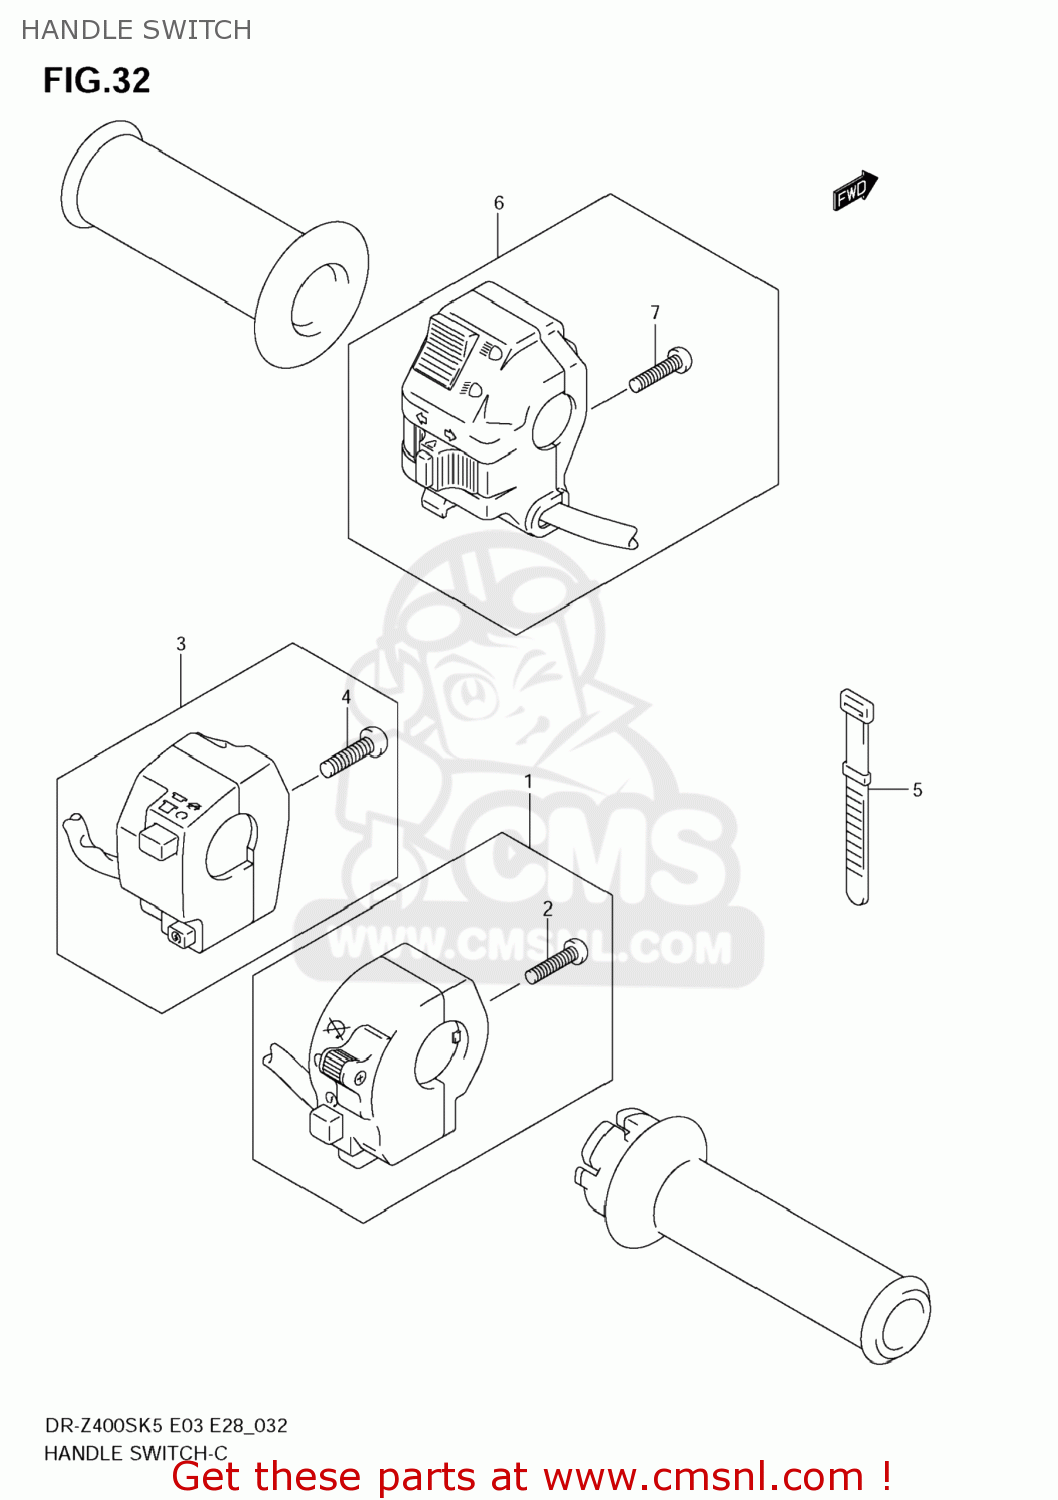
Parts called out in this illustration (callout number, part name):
1	SWITCH ASSY,HANDLE,R
2	SCREW
3	SWITCH ASSY,HANDLE,R
4	SCREW
5	CLAMP(L:120)
6	SWITCH ASSY,HANDLE,L
7	SCREW
